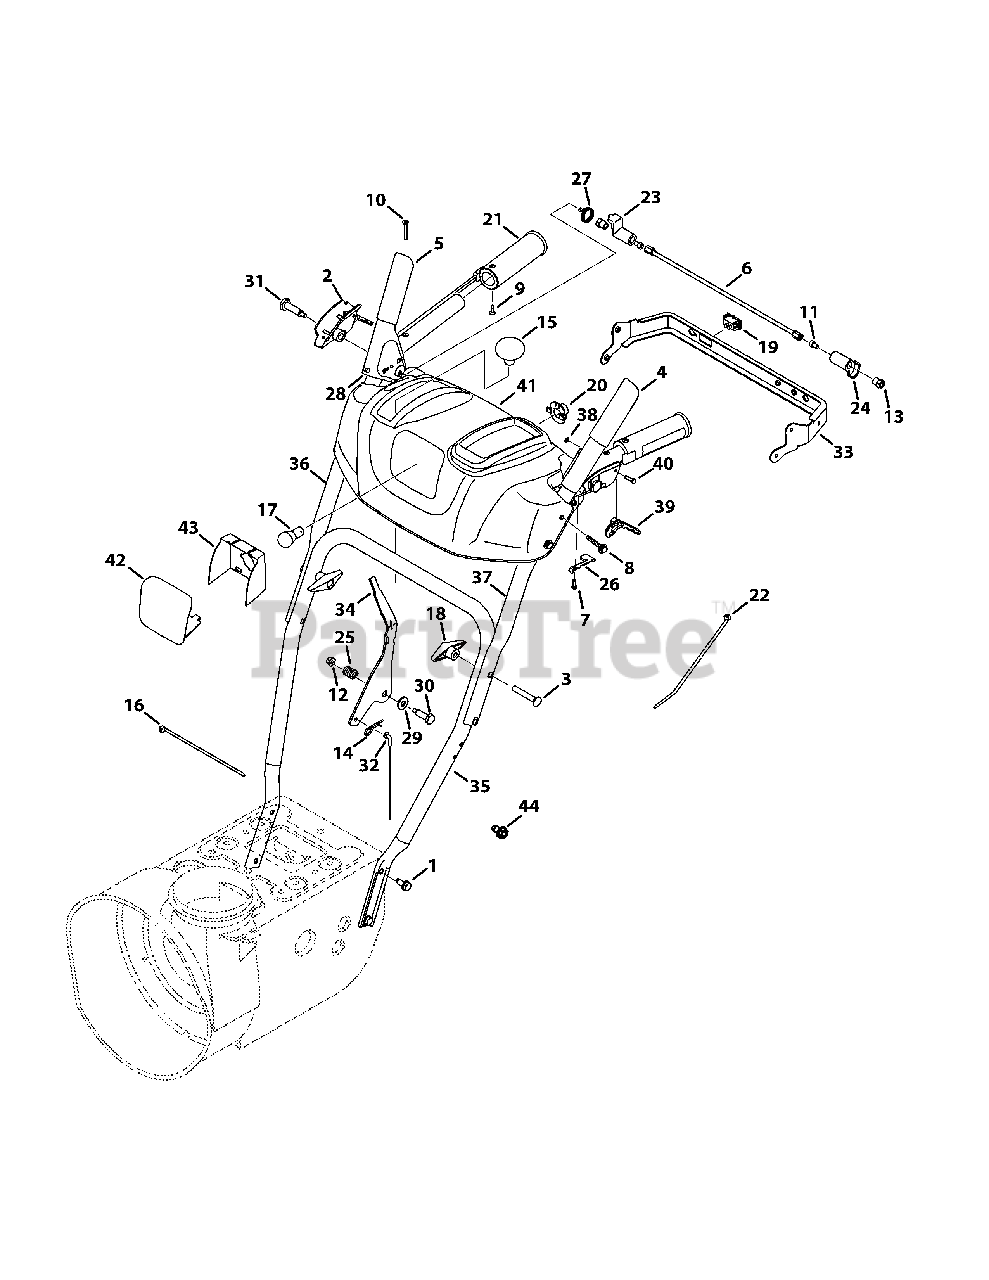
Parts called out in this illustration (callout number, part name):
1	Screw, Taptite, 5/16-18 x .750
2	Clutch Lock, RH
2	Clutch Lock, LH
3	Screw, Carriage, 5/16-18 x 2.50
4	Auger Engage, Black, LH
5	Drive Engage, Black, RH
6	Pivot Rod
7	Screw, Plastite, 8-16 x .50
8	Screw, Taptite, 1/4-20 x 1.625
9	Screw, 10-16 x 0.625
10	Screw, 10-24 x 1.375
11	Screw, 1/4-20 x .50
12	Nut, Flangelock, 1/4-20
13	Nut, Hex, 1/4-20
14	Click Pin, .092 x 1.64
15	Shift Knob
16	Cable Tie, 7"
18	Wing Knob, 5/16-18
19	Heated Grip Switch
20	Lamp Socket
21	Heated Grip
22	Cable Tie, Push Mount
23	Plate, Lock
24	Cam, Clutch Lock
25	Compression Spring, .39 x .60 x .88
26	Clutch Lock Spring
27	Torsion Spring, 0.8156 x .3038
28	Rubber Bumper
29	Washer, Flat, .385 x .87
30	Screw, Shield, .374 x 1.05
31	Screw, Shoulder, .437 x 1.345 x 1/4-20
32	Speed Selector Cable
33	Panel Bracket
34	Shift Lever
35	Lower Handle
36	Upper RH Handle
37	Upper LH Handle
38	E-Ring
39	Steering Trigger Control
40	Steering Trigger Pin, 3/16
41	Handle Panel, Gray
42	Lens Panel
43	Lens Label
44	Screw, TT, 1/4-20 x .500 (For ground wire)
